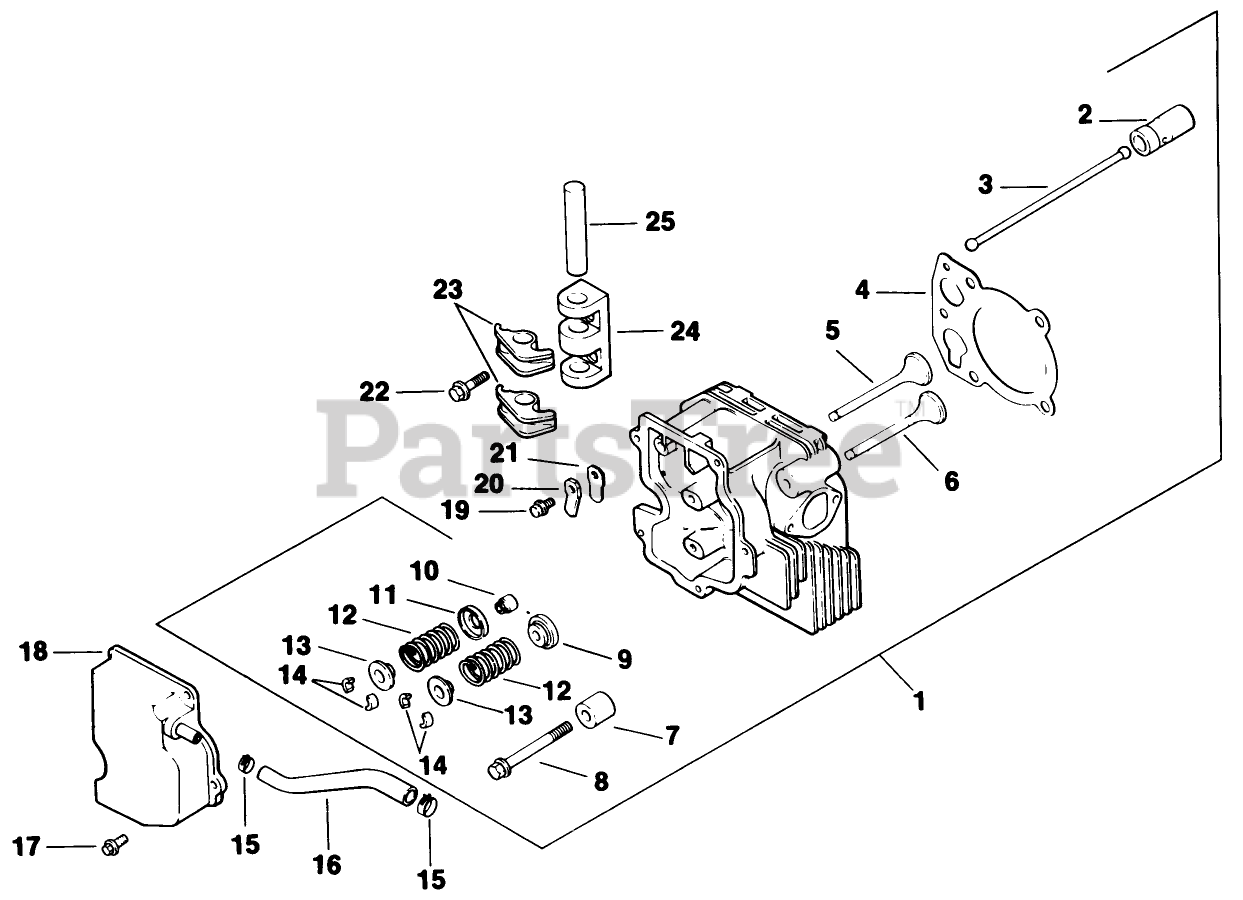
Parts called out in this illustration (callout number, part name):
1	Kit Cylinder Head
2	Lifter-Valve
3	Rod-Push
4	Gasket-Cylinder Head
5	Valve-Intake STD (Only On: 72042, 72063, 72062, 72043)
6	Valve-Exhaust STD (Only On: 72042,72043,72062,72063)
7	Spacer-Head Bolt
8	Screw-Cylinder Head
10	Seal
11	Retainer-Spring
12	Spring-Valve Intake (Only On: 72042, 72063, 72062, 72043)
13	Cap-Valve Spring
14	Kit-Retainer
15	Clamp
16	Hose-Breather (Only On: 72042, 72063, 72062, 72043)
18	Cover-Valve W/Nipple (Only On: 72042, 72063, 72062, 72043)
20	Retainer-Reed
23	Arm-Rocker
24	Bridge-Rocker Arm
25	Shaft-Rocker Arm
